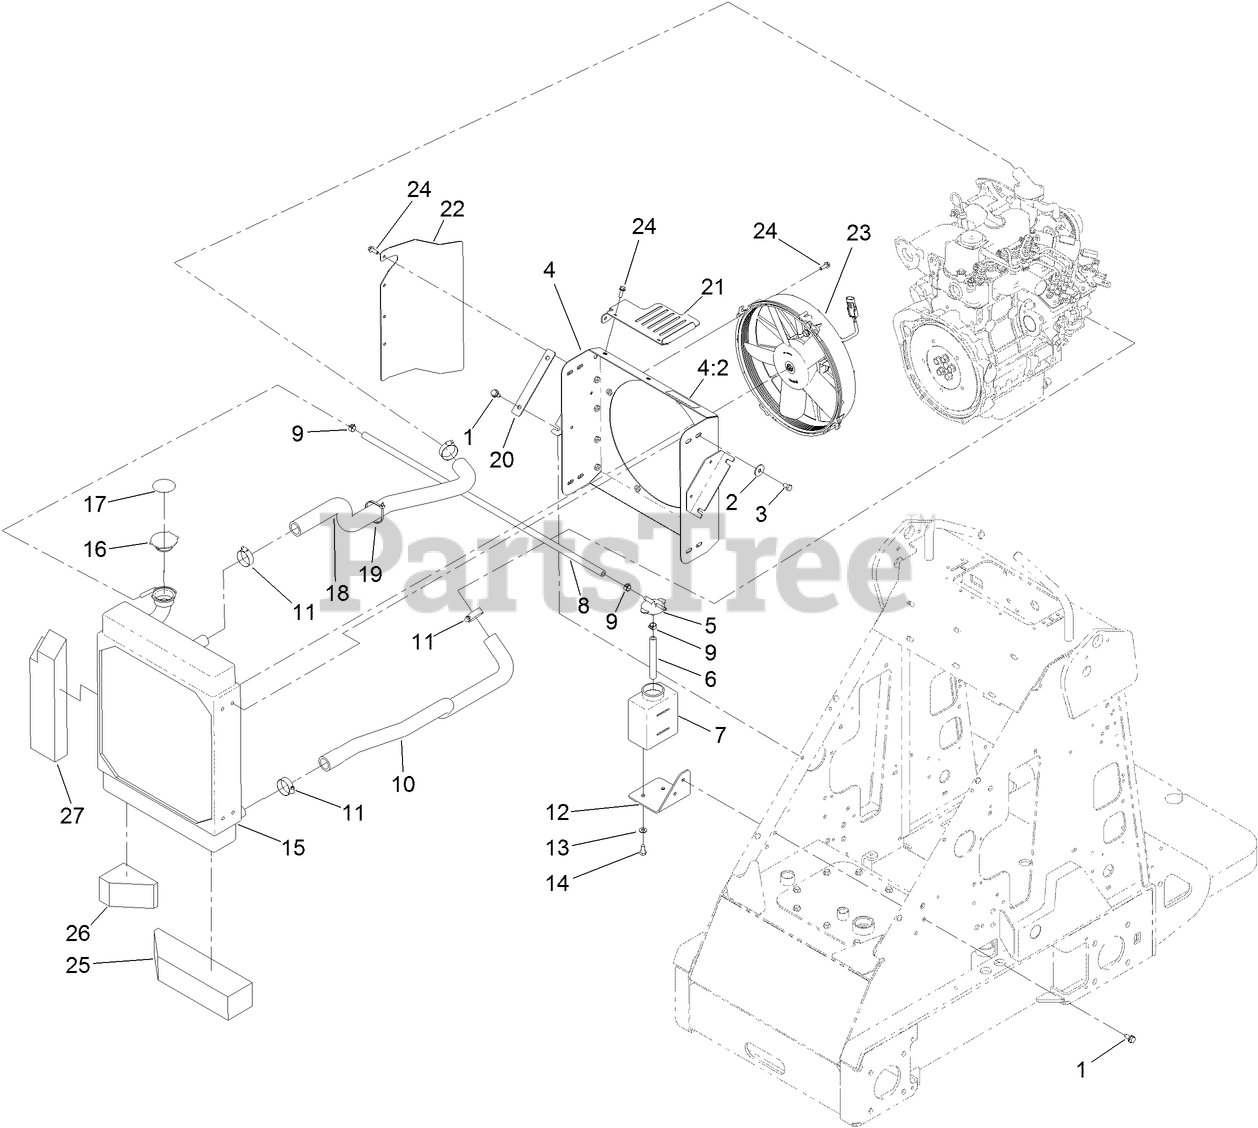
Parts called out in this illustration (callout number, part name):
1	SCREW-HWHTF
2	WASHER-FLAT
3	SCREW-HH
4	MOUNT-RADIATOR
4:2	DECAL-WARNING
5	CAP-TANK, OVERFLOW
6	HOSE-FUEL
7	TANK-OVERFLOW
8	HOSE-FUEL
9	CLAMP-HOSE
10	HOSE-RADIATOR, LOWER
11	CLAMP-HOSE
12	MOUNT-TANK, OVERFLOW
13	WASHER-PLAIN
14	BOLT
15	RADIATOR
16	CAP-RADIATOR
17	DECAL-WARNING
18	HOSE-RADIATOR, UPPER
19	TIE-CABLE
20	PLATE-CLAMP, RADIATOR
21	FAN-GUARD
22	PLATE-BAFFLE
24	SCREW-HHF
25	FOAM-SEAL
26	FOAM-SEAL
27	SEAL-FOAM
